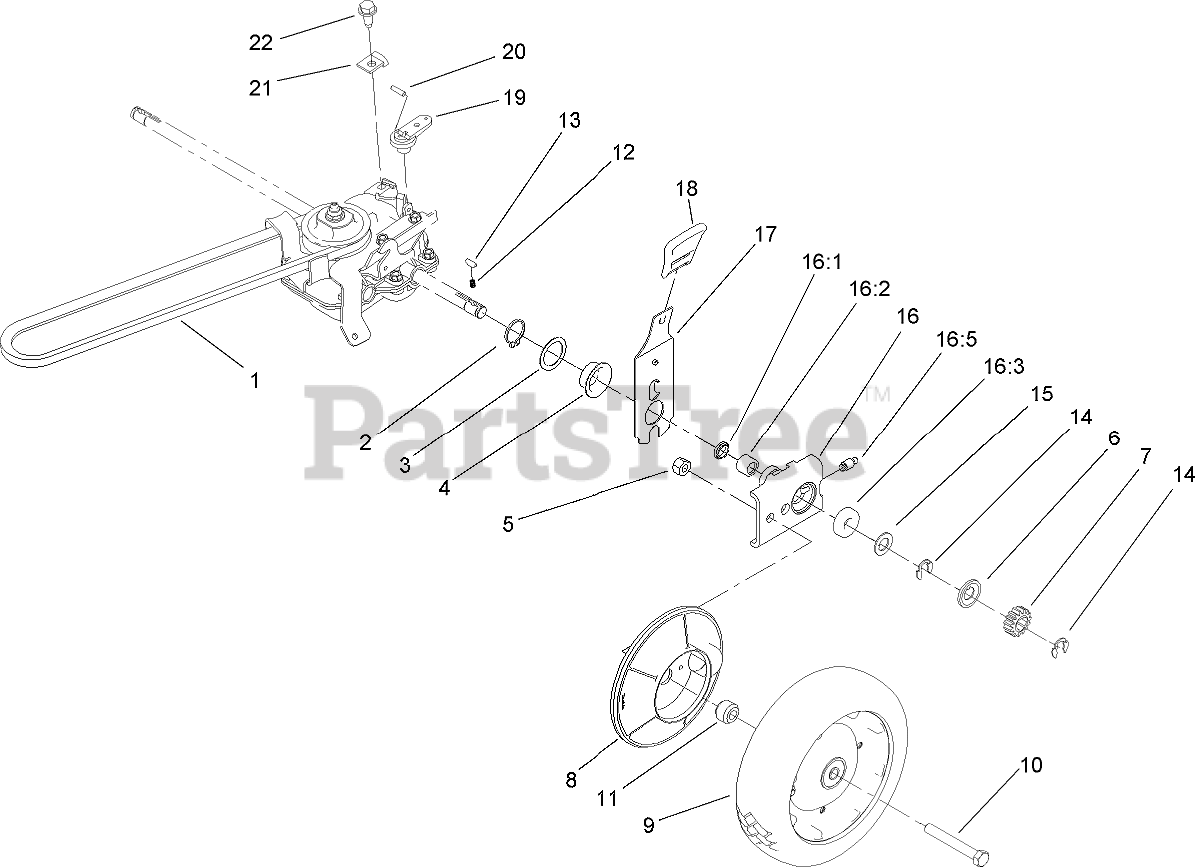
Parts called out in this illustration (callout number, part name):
1	V-BELT
2	RING-RETAINING
3	WASHER
4	CAP-END
5	NUT-LOCK, CONE
6	WASHER-THRUST, OUTER
7	GEAR-PINION
8	COVER-WHEEL
9	Wheel And Tire ASM
10	SCREW-HH
11	SPACER-COVER, WHEEL
12	SPRING-COMPRESSION
14	RING-RETAINING
15	WASHER-THRUST, OUTER
16	PIVOT ARM ASM
16:1	SEAL-OIL
16:2	BEARING-ROLLER
16:3	BEARING-WHEEL
17	REAR SPRING ARM ASM
18	KNOB-HOC
19	LEVER-SHIFT
20	PIN-COIL
21	CLAMP-CABLE
22	SCREW-HWHTF
